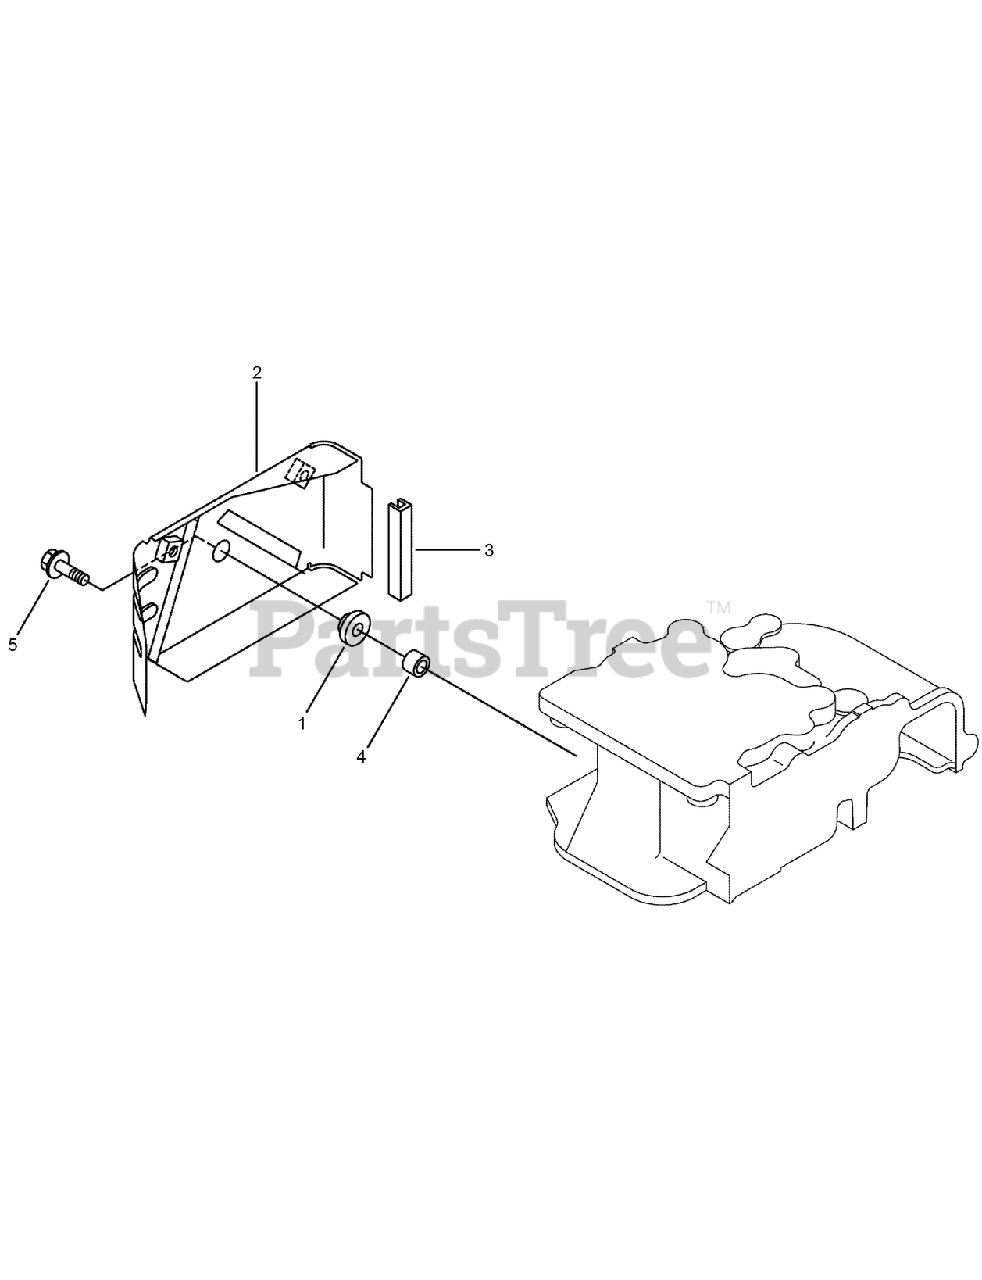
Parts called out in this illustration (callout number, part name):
1	GROMMET
2	COVER-SIDE, B
3	RUBBER, SEAL
4	COLLAR
